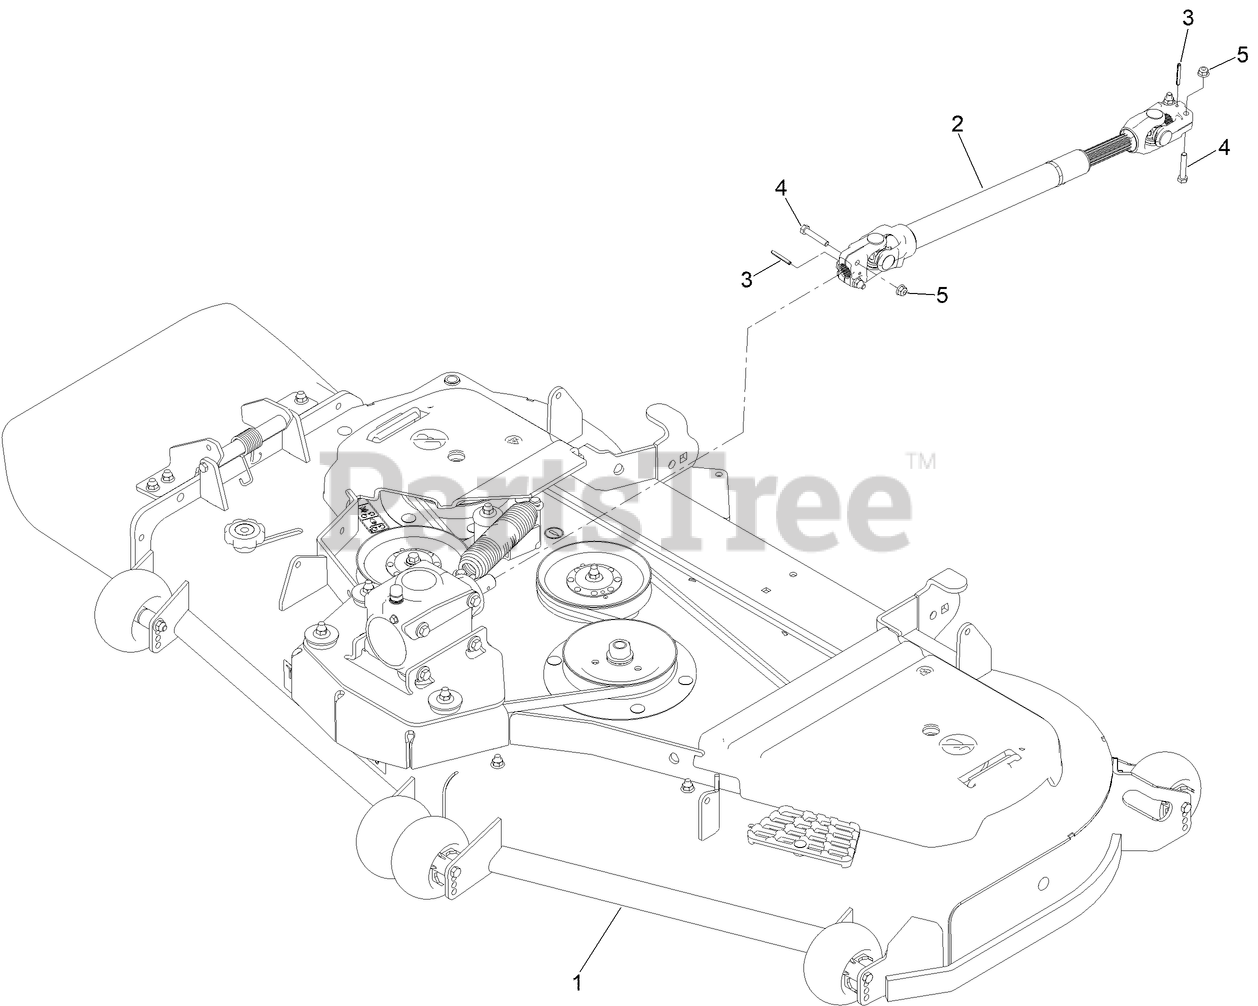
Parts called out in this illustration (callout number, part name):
2	DRIVESHAFT ASM
3	PIN-ROLL
4	SCREW-HH
5	NUT-HF, NI
